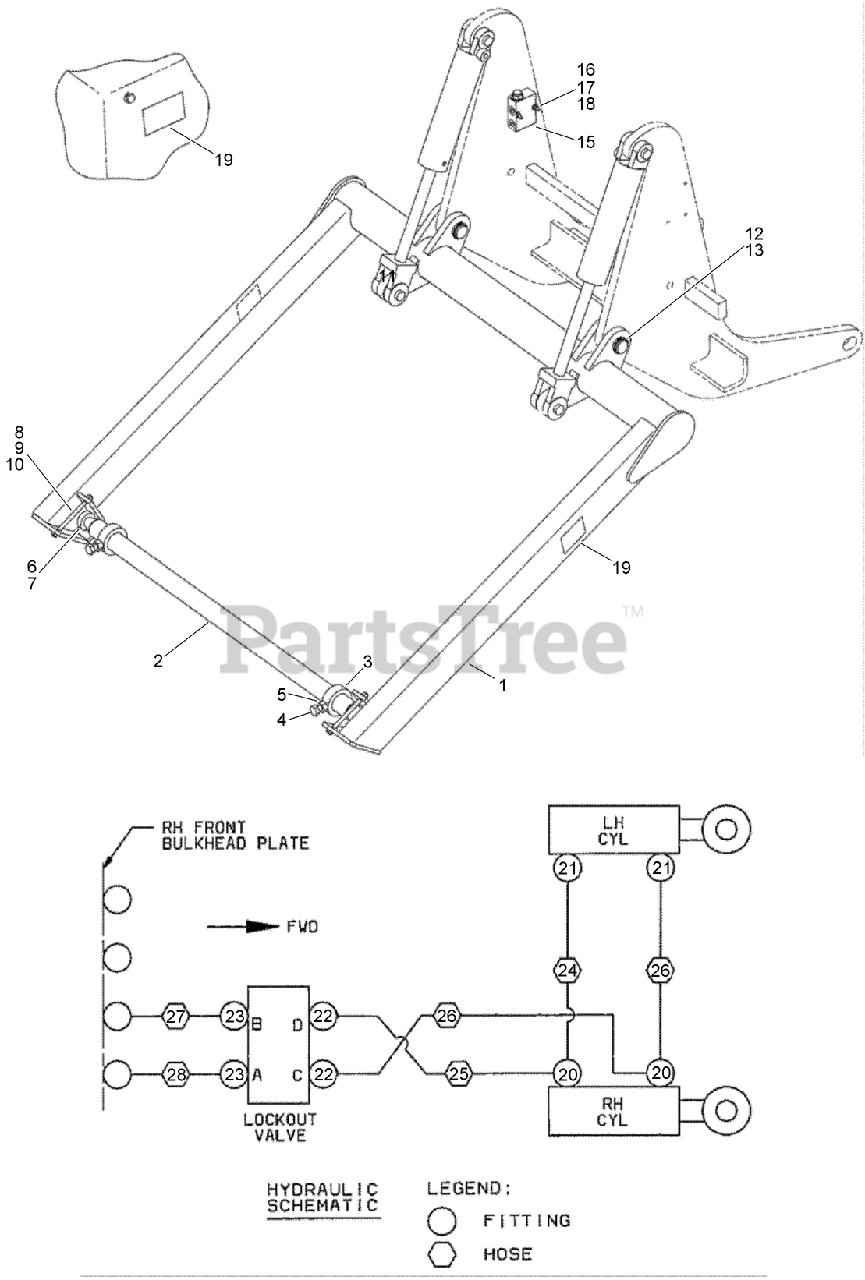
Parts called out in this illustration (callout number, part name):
1	FRAME-Reel Carrier
2	SHAFT-Reel Carrier
3	COLLAR-Reel Carrier Shaft
4	BOLT-Hex Hd 5/8 x 1-1/2 GR5 ZND
5	NUT-HEX, JAM
6	BEARING-Ball, Reel Carrier Shaft
7	RING-3/4, Bearing Retaining
8	BOLT-Hex Hd, 3/8 NC x 5-1/4 inch GR5
9	WASHER-FLAT
10	NUT-HEX
11	CYLINDER-64 (2-1/2) ID x 203 mm (8 inch) Stroke, Lift
15	HYD LOCKOUT VALVE ASM
16	BOLT-Hex, 1/4 NC x 3 inch GR5
17	WASHER-FLAT
18	NUT-Prev Trq 1/4 GRC PHC Direct
19	DECAL-Lift Rating (1000 lbs)
20	FITTING-TEE
21	CONNECTOR-Str Thd 3/8, 37FL-ORB 3/8
22	ELBOW-90 Adj 37FL, 3/8 x 1/2 Tube
23	ELBOW-8MO x 6MJ 45 Deg Adapter
24	HOSE-Hydraulic
25	HOSE-Hydraulic
26	HOSE-Hydraulic
27	HOSE-Hydraulic
28	HOSE-Hydraulic
